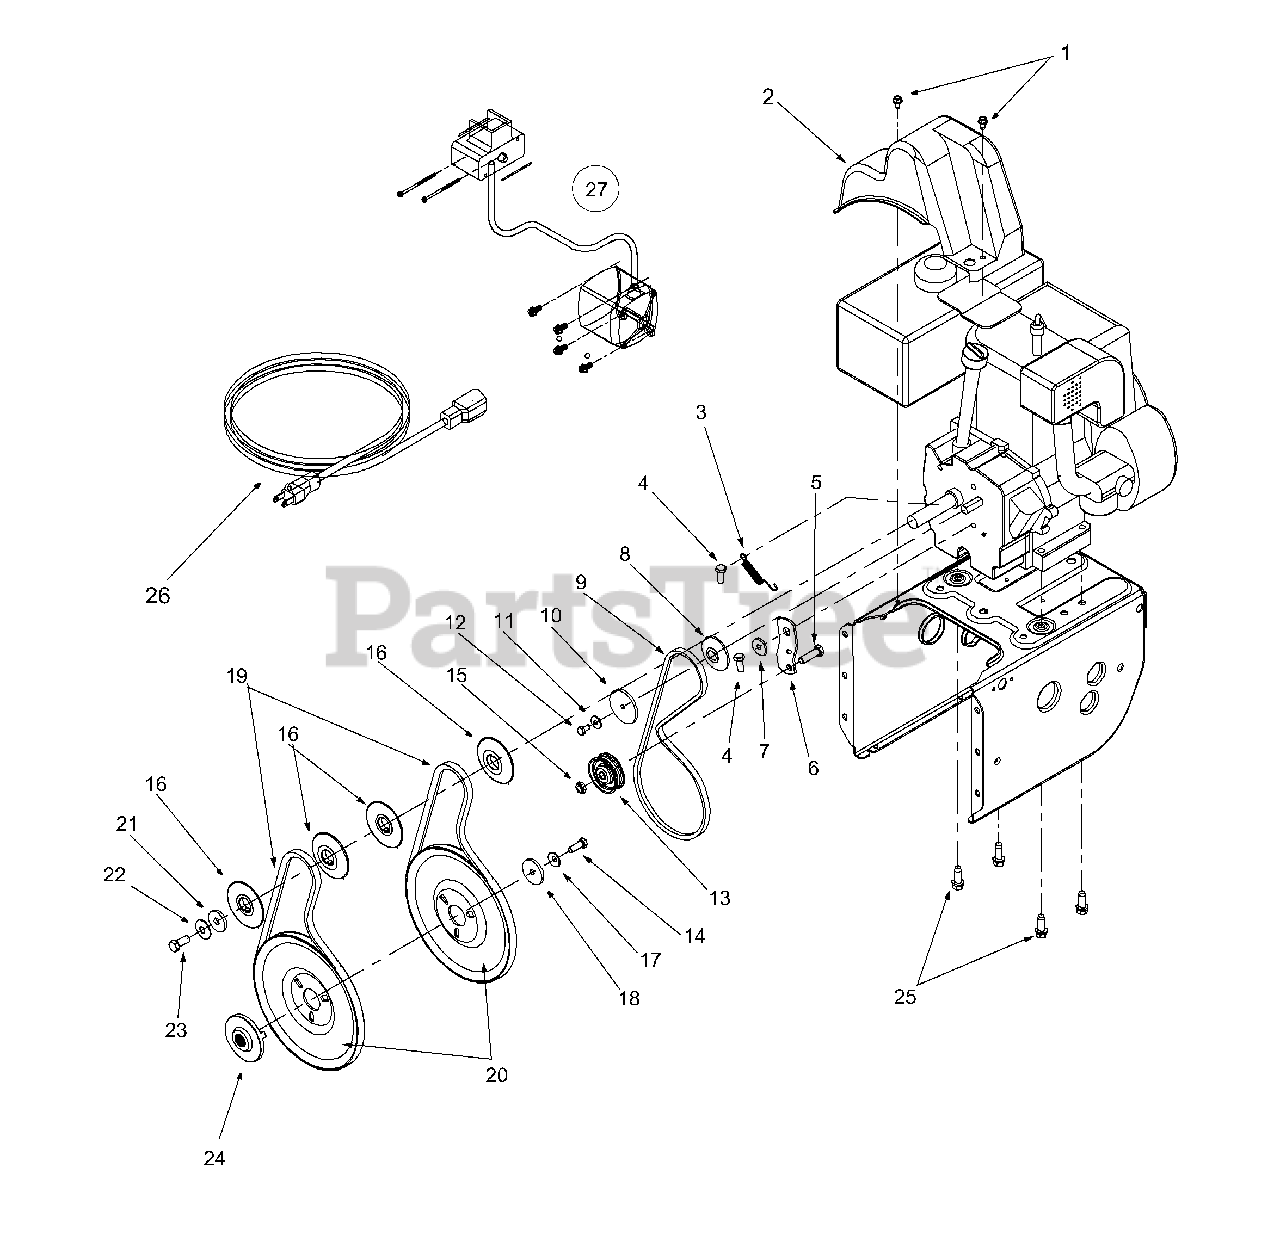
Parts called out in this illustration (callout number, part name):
1	Hex Washer Screw 1/4-20 x .50
2	Belt Cover
3	Extension Spring
4	Hex Screw 5/16-24 x .75
5	Hex Cap Screw 3/8-16 x 1.25
8	Pulley Half
9	V-Belt
10	Pulley Half
11	Bell Washer
12	Hex Cap Screw 1/4-28 x .50
13	Flat Idler
14	Lock Hex Cap Screw 5/16-24
15	Lock Jam Nut 3/8-16
16	Pulley Half
17	Bell Washer
18	Flat Washer
19	Belt
20	Auger Pulley
21	Flat Washer 3/8 x 1.25 OD
22	Bell Washer
23	Hex Cap Screw 3/8-24
24	Adapter Pulley
25	Hex Screw 3/8-16 x 1.0
26	Extension Cord
27	Electric Start Kit
